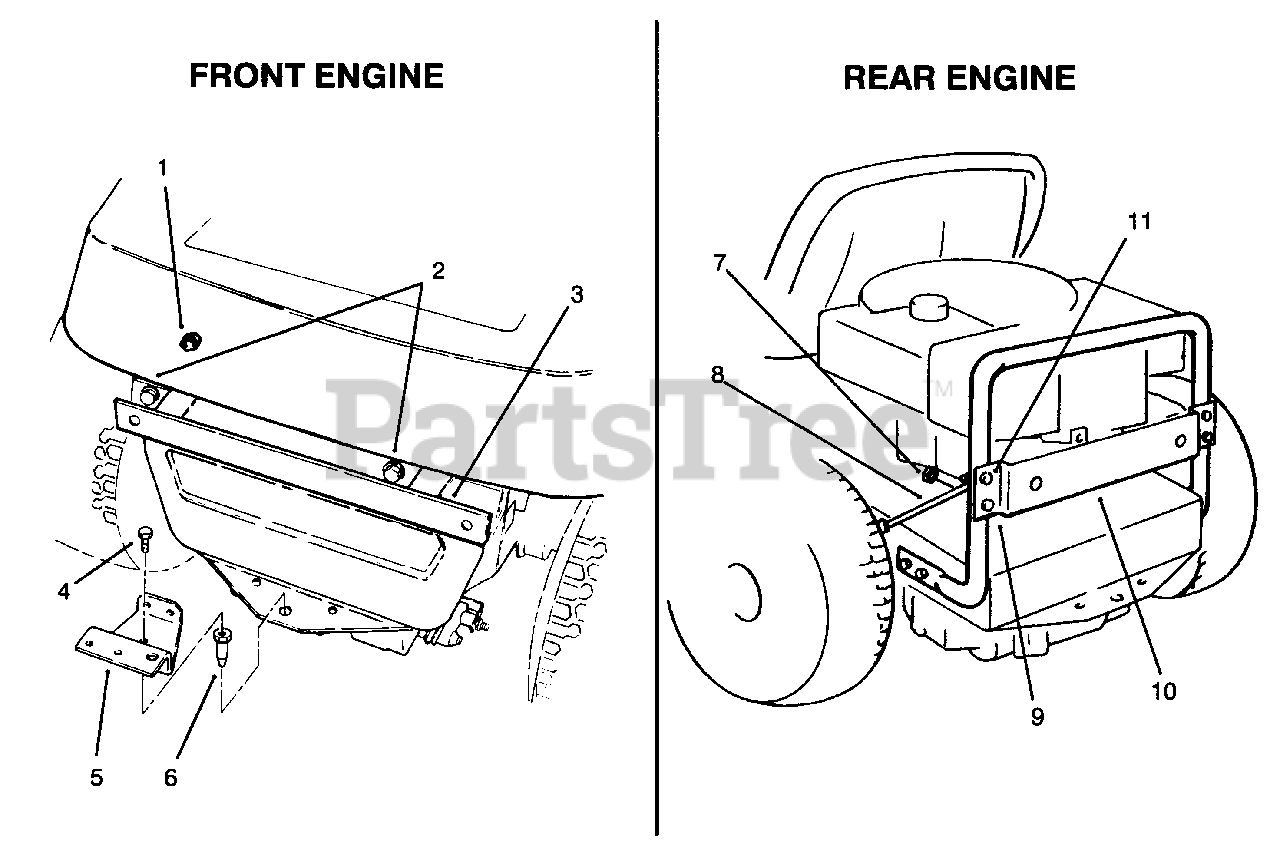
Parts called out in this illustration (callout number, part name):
2	Capscrew
3	Bracket-Channel
4	Capscrew
5	Bracket-Bagger Mounting
6	Pin-Mounting, Lower
8	Brace-Bagging
9	Capscrew
10	Plate-Bagging Kit
11	Capscrew
